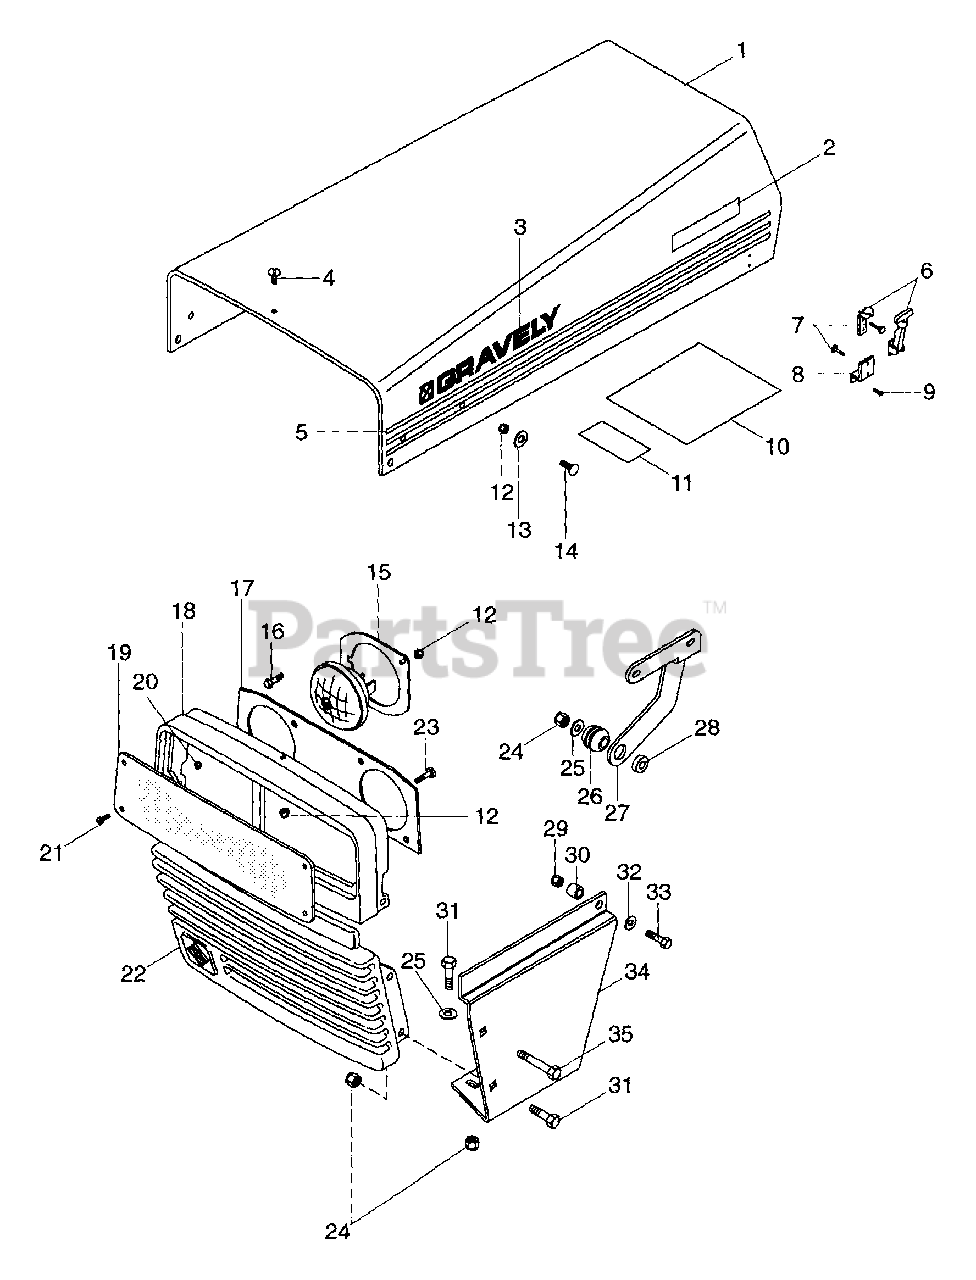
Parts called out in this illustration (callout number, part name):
1	Hood, Silk Screen
2	Decal, Model 14-G
2	Decal, Model 16-G
2	Decal, Model 18-G
2	Decal, Model 20-G
3	Decal, Gravely Logo
4	Screw-Machine .25-20
5	Gravely Name/Logo/Stripe Decal
6	Latch, Flexible
7	Rivet .125 x .245
8	Bracket, Hood Latch Mounting
9	Screw-Machine 8-18 x .375
10	Decal-Maintenance
11	Decal-E-System Warning
12	Nut-Locking-Nylon .250-20 Grade 2
13	Washer-Flat .281 x .625 x .065
14	Bolt-Round Head Square Neck .25-20 x .75
15	Head Light Retainer Ring
16	Bolt-Hex .25-20 x 1.000 Grade 5
17	Panel, Headlight Reflector
18	Bezel, Headlight
19	Panel, Headlight Lense
20	Nut-Locking 10-24
21	Screw-Machine 10-24 x .750
22	Grill
23	Screw-Tapping .25-20 x .50
24	Nut-Locking-Nylon .375-16 Grade 2
25	Washer-Flat-Steel .438 x 1.0 x .083
26	Grommet
27	Left Hand Hood Hinge
27	Right Hand Hood Hinge
28	Spacer
29	Nut-Locking-Nylon .312-18 Grade 2
30	Bushing, Sleeve .406 x 1.00 x 1.00
31	Bolt-Hex .38-16 x 1.00 Grade 5
32	Washer-Flat-Steel .344 x .688 x .065
33	Bolt-Hex .31-18 x 1.75 Grade 5
34	Panel, Side Left Hand
34	Panel, Side Right Hand
35	Bolt, Hex .38-16 x 2.00 Grade 5
